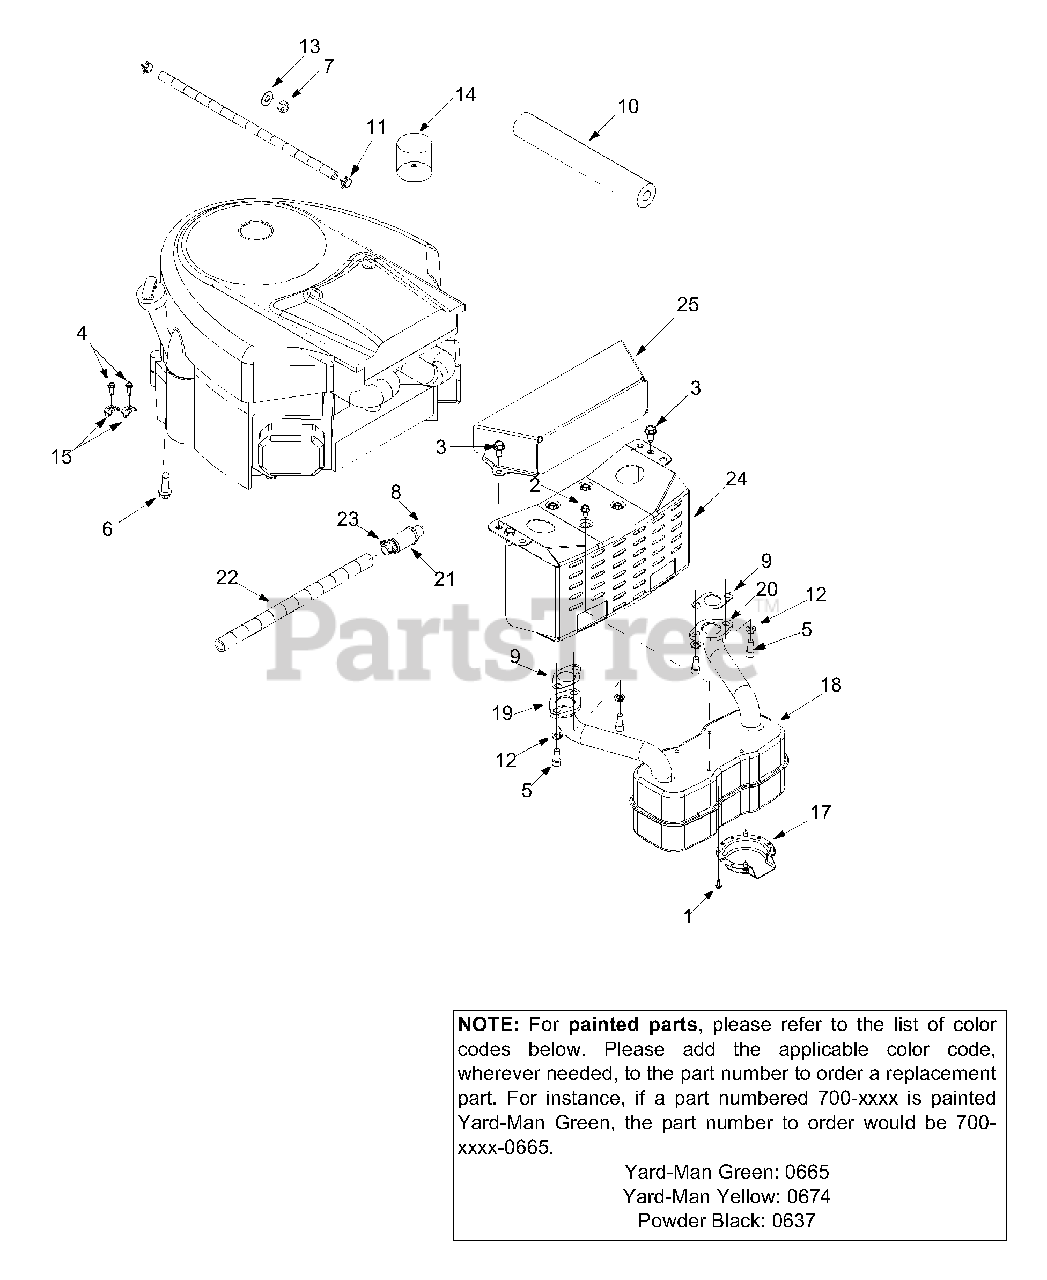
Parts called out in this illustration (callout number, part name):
1	Self-tapping Screw, #8-18 x .50"
2	Self-tapping Screw, 1/4-20 x .50"
3	AB Screw 5/16-12 x 0.75"
4	Screw, #10-32 x .625
5	Socket Cap Screw, 5/16-18 x .625
6	TT Screw 3/8-16 x 1.250"
7	Hex Nut 3/8-16
8	Sealant
9	Exhaust Gasket
10	Foam
11	Hose Clamp
12	Lock Washer
13	Flat Washer
15	Casing Clamp
17	Deflector: Muffler
18	Muffler: Dual Inlet
19	Exhaust Pipe RH
20	Exhaust Pipe LH
21	Oil Drain
22	Hose: Oil Drain Extension
23	Oil Drain Cap
25	Heat Shield
